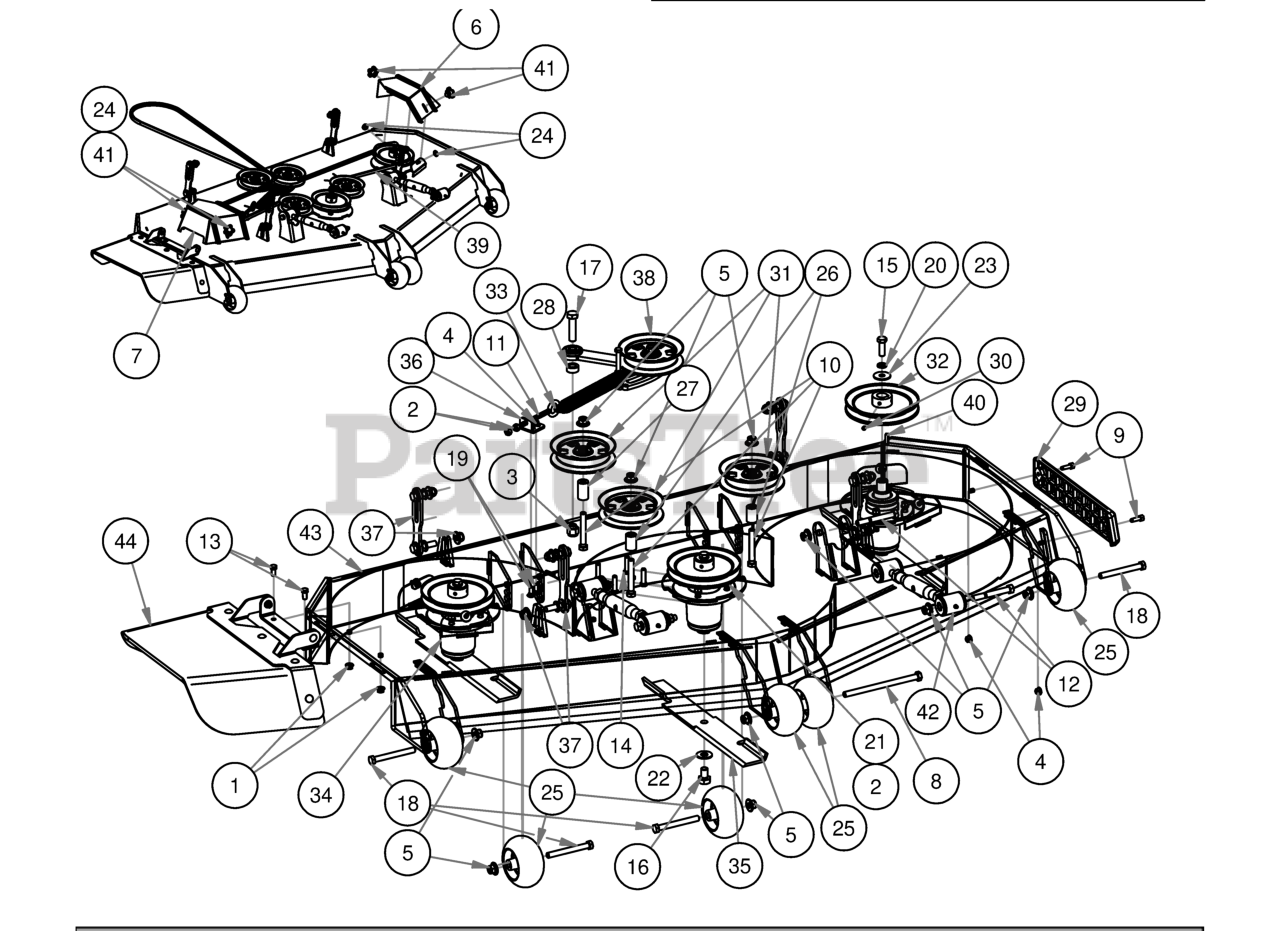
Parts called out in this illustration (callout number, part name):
1	3/8" Flange Nut
2	3/8" Hex Nut
3	5/8 Std NC Nylock Nut
4	5/16" Nylon Flange Nut
5	1/2-13 Nylon Flange Nut
6	2019 72" Left Outlaw Gen2 Pulley Cover
7	2019 72" Right Outlaw Gen2 Pulley Cover
8	1/2-13 x 8 Hex Bolt Grade 5
9	5/16-18 x 1 GR 5 Hex Bolt Zinc
10	1/2 x 3 1/2 Flange Bolt Grade 8
11	4" 3/8-16 Eye Bolt
12	1/2" x 4" Bolt (Grade 8)
13	3/8" x 3/4" Hex Bolt
14	3/8 x 1.5" Bolt
15	1/2"-20 x 1 1/2 - Grade 5 Fine Thread Bolt
16	5/8" x 1 1/2" Grade 8 Hex Bolt (Fine)
17	5/8" x 2 1/2" Grade 5 Hex Bolt (Coarse)
18	1/2" x 4 1/2" Bolt
19	5/16" x 7/8" Carriage Bolt
20	1/2" Lock Washer
21	3/8" Lock Washer
22	5/8'' Flat Washer
23	1/2" Belleville Washer
24	.360 ID Plastic Washer-Black
25	2019 Deck Wheel
26	.502 ID X .750 OD X 1.500 Long Spacer
27	1 3/4" Pulley Spacer
28	5/8" x 1/" Collar W/One Set Screw
29	REVISED TRIM BUMPER_20180226
30	5/16 Set Screw
31	5-3/4 Idler Pulley
32	7" Deck Pulley
33	2019 Outlaw Gen2 Deck Spring
34	OUTLAW SPINDLE ASSEMBLY
35	72" High Lift Fusion Blade
36	2019 Deck Eye Bolt Tab
37	Deck Hangar Assembly
38	2019 Rebel Rogue Deck Idler
39	B202 Belt for 72" Outlaw
40	1/4" x 1" Key
41	5/16" Knob
42	Turnbuckle
43	2019 Sloped 72" Deck
44	2019 Outlaw Gen2 Chute Assembly
